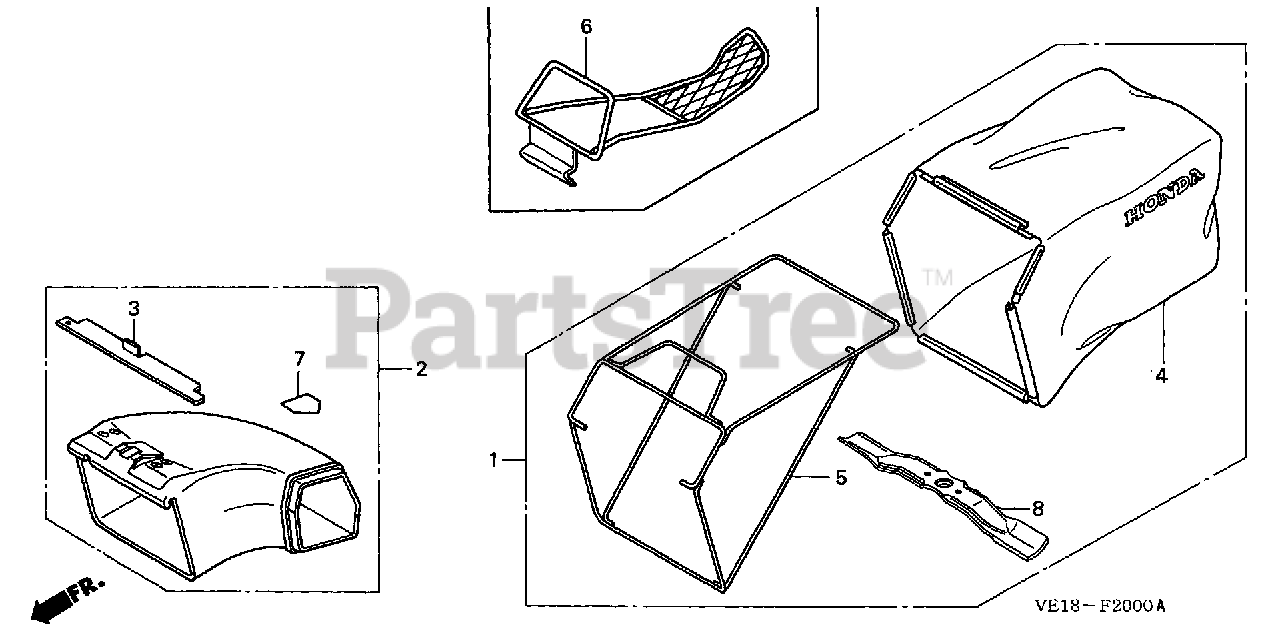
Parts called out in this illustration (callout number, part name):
2	CHUTE KIT, SIDE DISCHARGE
3	BRACKET, MOUNTING (NOT AVAILABLE)
4	FABRIC, GRASS BAG
5	FRAME, BAG
6	SHREDDER, LEAF
7	LABEL B, HOUSING CAUTION (ENGLISH)
7	CAUTION C, HOUSING
